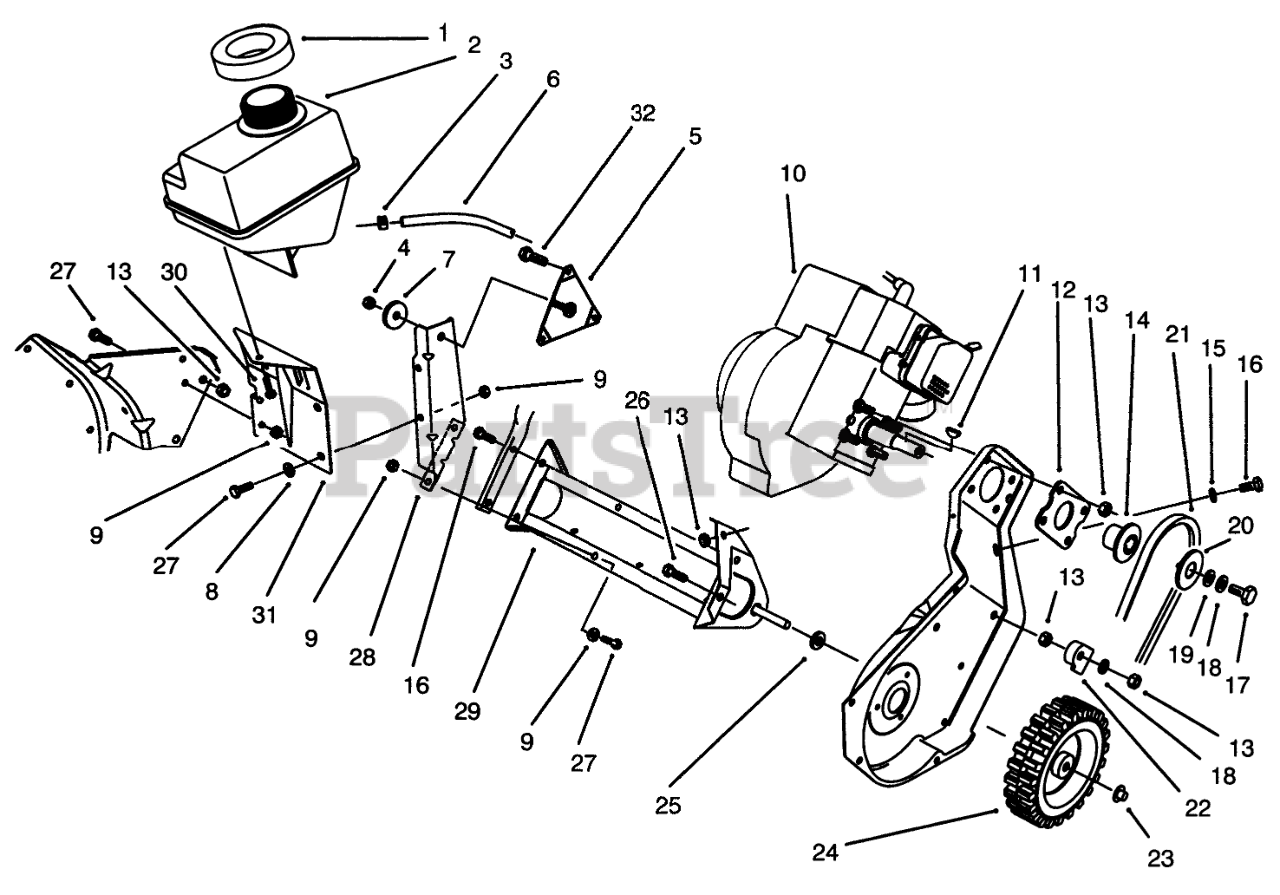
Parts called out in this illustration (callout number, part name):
1	SEAL-FOAM
2	Tank-Gas
3	Clamp
4	NUT-LOCK, NI
5	BRACKET AND STUD ASM
6	LINE-FUEL
7	WASHER-SUPPORT, ENGINE
8	WASHER-FLAT
9	NUT-LOCK, NI
11	KEY-WOODRUFF
12	Plate Engine
13	NUT-LOCK, NI
14	Hub-HALF SHEAVE
15	WASHER-PLAIN
16	SCREW-HH
17	SCREW-HH
18	WASHER-BELLEVILLE
19	WASHER-FLAT
20	CAP-HALF SHEAVE
21	V-BELT
22	GUIDE-CABLE
23	RETAINER-PUSH ON
24	WHEEL
25	SPACER-PLASTIC
26	SCREW-HH
27	SCREW-HH
28	Support-Engine
29	Frame Assembly
30	SCREW-SHWH, THREAD FORMING
31	Bracket-Fuel Tank
32	SCREW X
